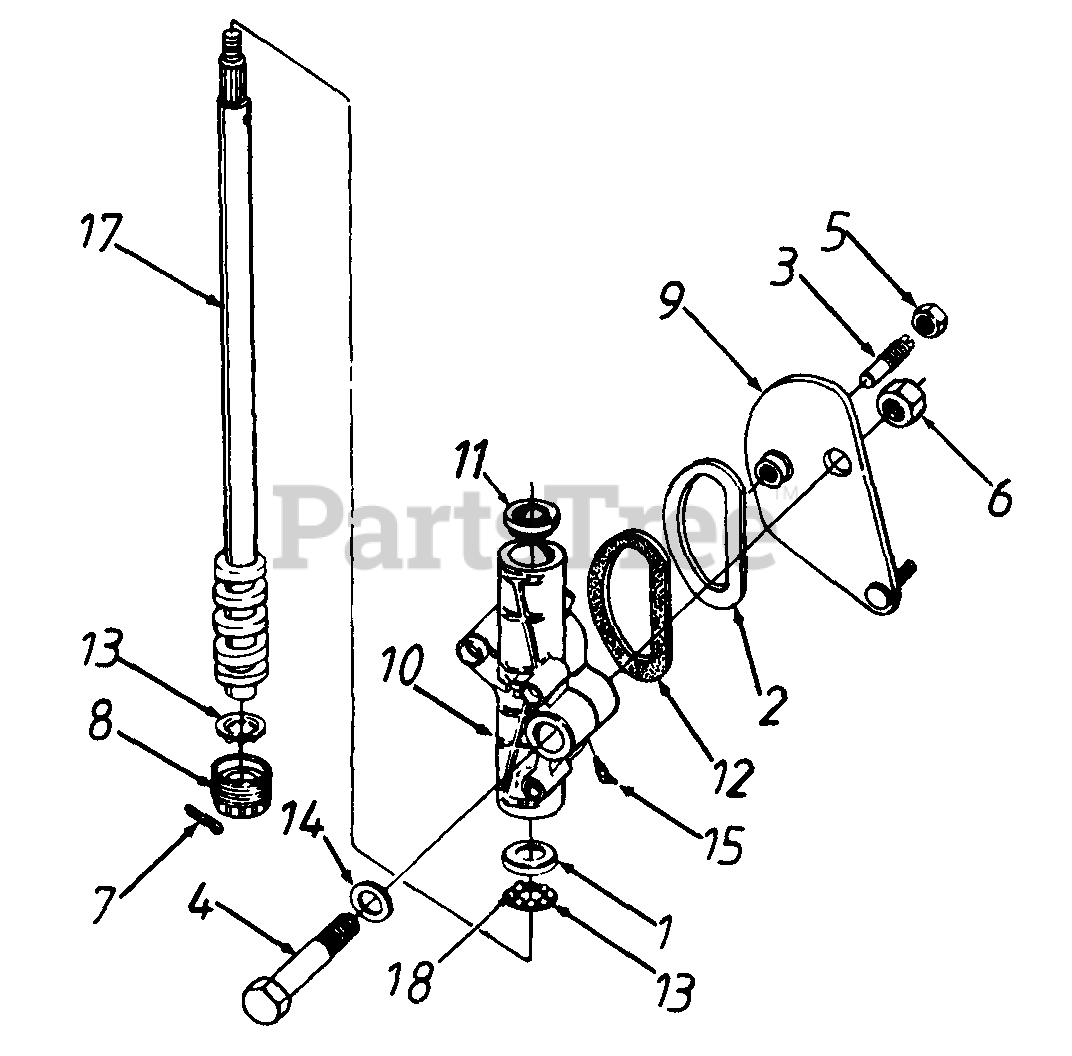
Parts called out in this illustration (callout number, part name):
1	Bearing Cup
2	Seal Retainer
3	Cam Follower
4	Pivot Shaft
5	Hex Jam Nut 9/16-18 Thd.
6	Hex Crown L-Nut 5/8-18 Thd.
7	Cotter Pin 1/8" Dia.
8	Adjustment Plug Ass'y.
9	Steering Arm Ass'y.
10	Steering Hsg. Bushing Ass'y.
11	Oil Seal
12	Seal
13	Ball Retainer
14	Fl-Wash. .781" I.D. x 1.25" O.D.
15	Grease Fltting
17	Steering Shaft Ass'y.
18	Ball Bearing
